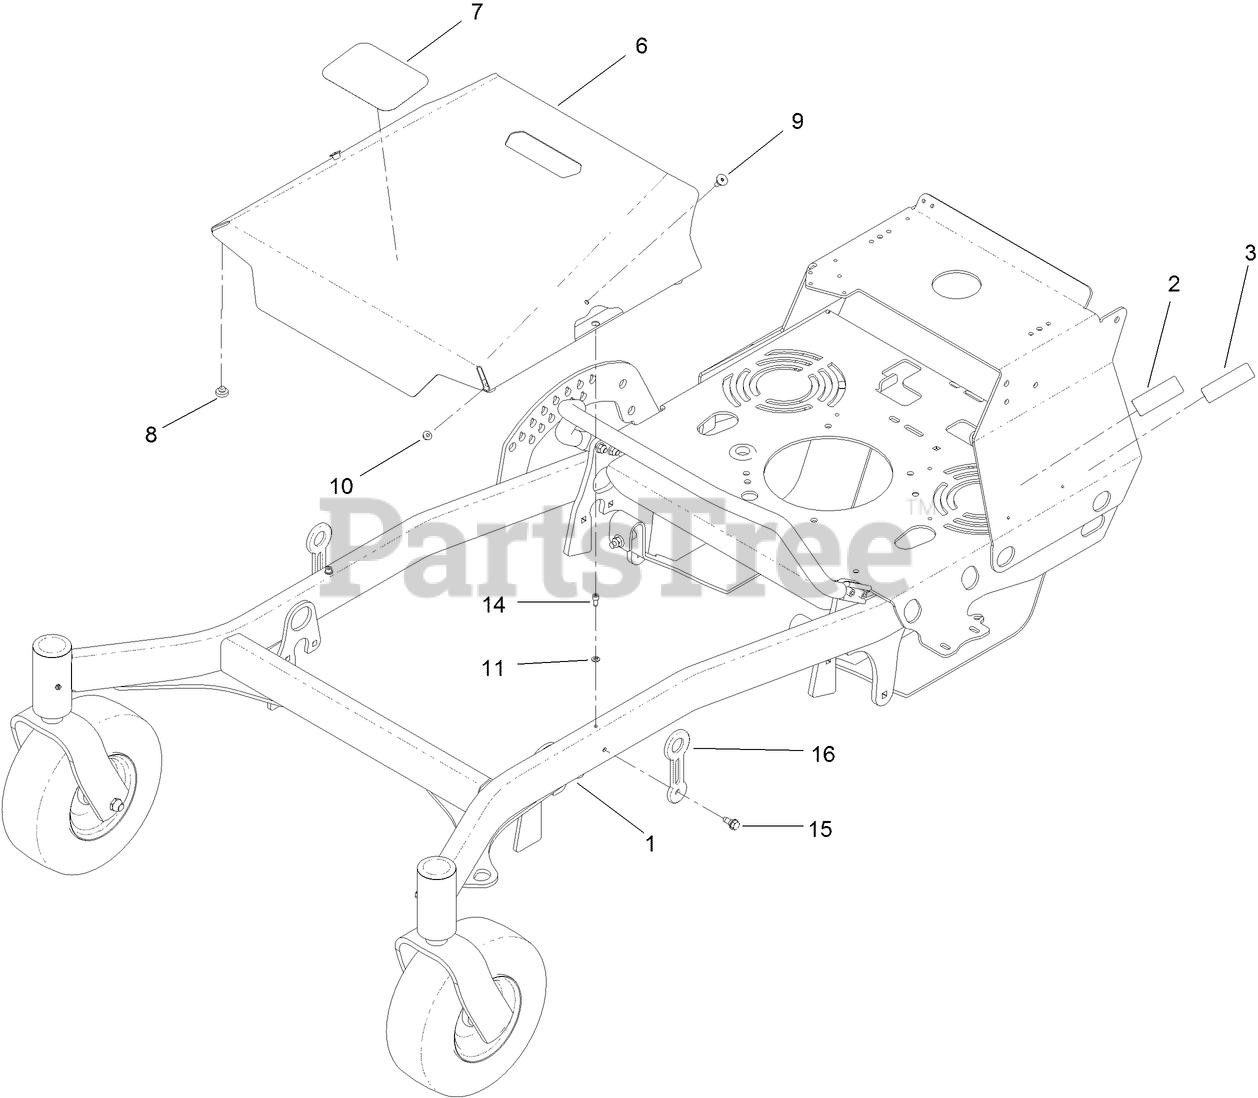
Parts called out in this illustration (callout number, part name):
1	FRAME ASSEMBLY
2	DECAL-EMISSIONS, CARB 2020
3	DECAL-ARRESTOR, SPARK
6	COVER-DECK,WIDE
7	DECAL
8	BUMPER
10	NUT-HF
11	WASHER-LOCK
14	SCREW-HSH, THREAD FORMING
15	SCREW-SHOULDER
16	LATCH-RUBBER
